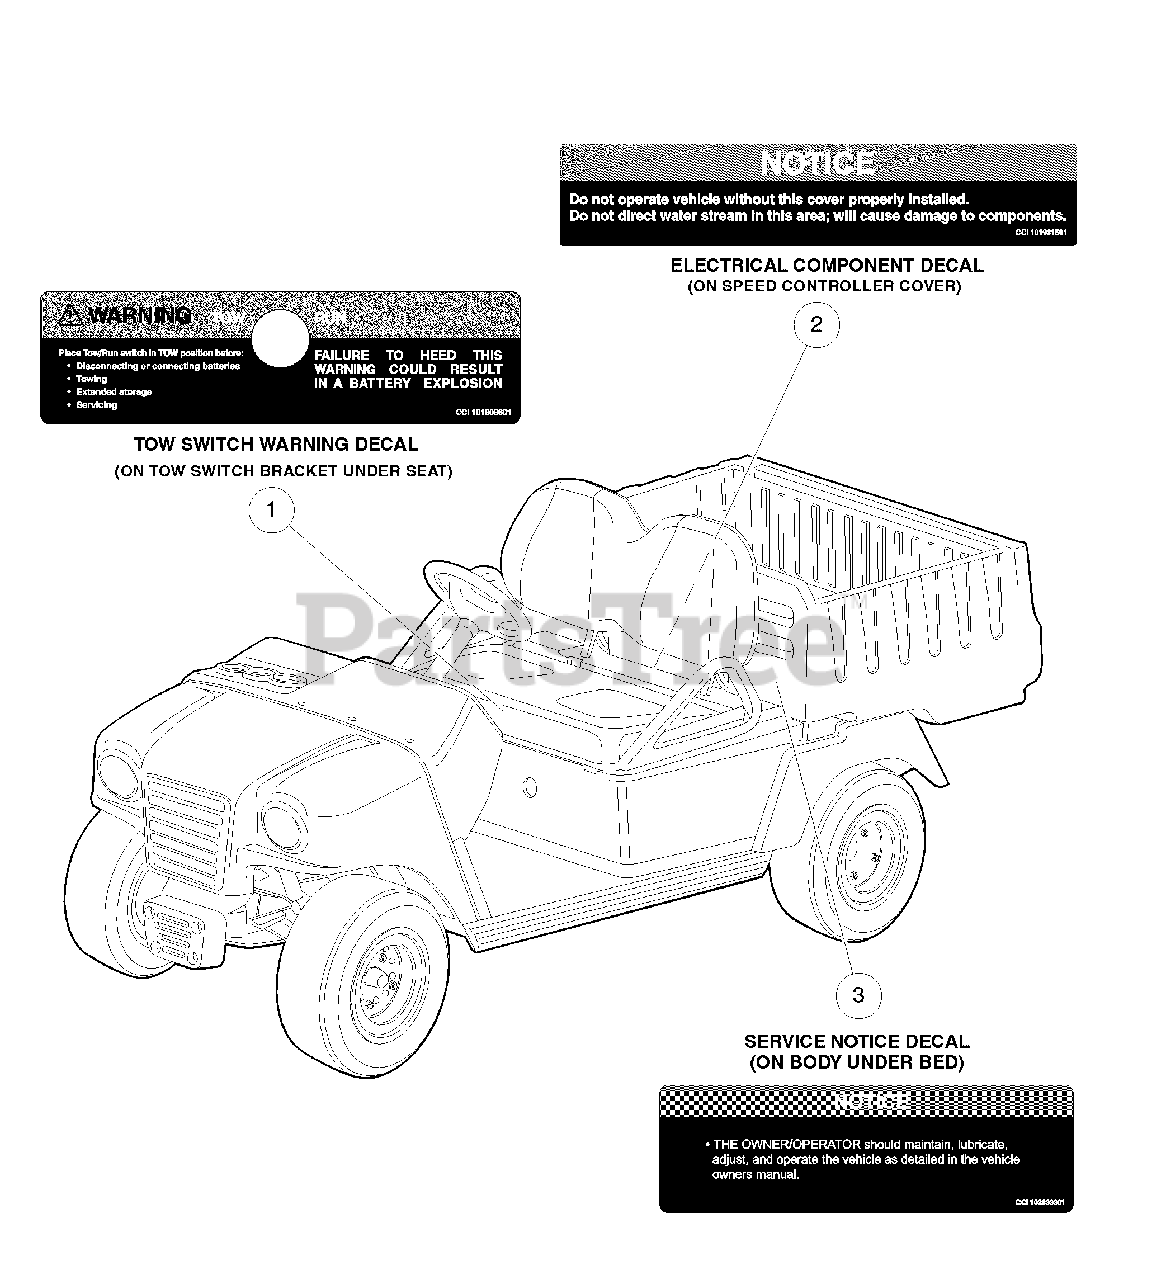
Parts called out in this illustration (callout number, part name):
1	Decal, Tow/Run Switch Warning
2	Decal, Component Cover
3	Decal, Maintenance
